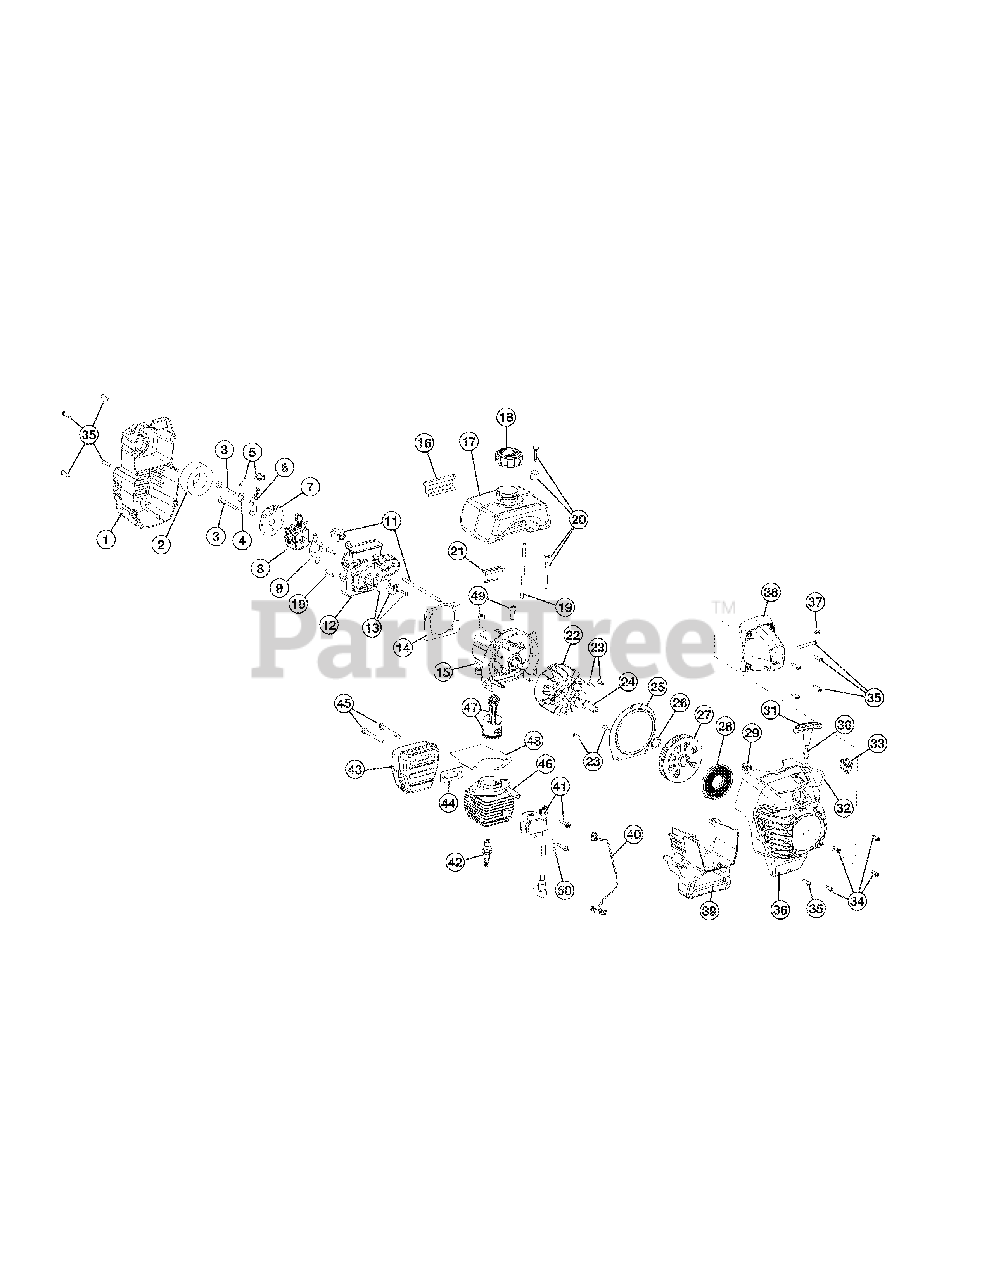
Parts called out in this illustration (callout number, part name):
1	Air Cleaner Cover Assembly (includes 2 & 35)
2	Air Cleaner Filter
3	Carburetor Mounting Screws
4	Wavey Washer
5	Choke Knob & Screw
6	Choke Lever Assembly (includes 5)
7	Choke Lever & Plate (includes 6)
8	Carburetor Assembly (includes 9 & 20)
9	Carburetor Gasket
10	Carb Mount Screw
11	Primer and Hose Assembly
12	Carburetor Mount Assembly (includes 10, 13 & 14)
13	Reed Assembly
14	Carburetor Mount Gasket
15	Crankcase Service Assembly (includes 10 & 23)
16	Rear Mounting Pad
17	Fuel Tank Assembly (includes 18 & 20)
18	Fuel Cap Assembly
19	Fuel Return Line
20	Fuel Line Assembly
21	Front Mounting Pad
22	Flywheel Assembly
23	Screw
24	Square Nut Drive
25	Pulley Retainer Assembly (includes 23 & 29)
26	Palnut
27	Recoil Pulley Assembly (includes 26 & 32)
28	Recoil Spring
29	Rope Guide Retainer
30	Pull Handle
31	Rope Guide
33	Switch Assembly (includes 40)
34	Housing Screw
35	Cover Screw
36	Starter Housing Assembly (includes 23, 25-32, 34 &35)
37	Anti-Rotation Screw
38	Clutch Cover Assembly (includes 35 & 37)
39	Shroud Extension and Stand (includes 35)
40	Wire Lead
41	Module Assembly
42	Spark Plug
43	Muffler Assembly (includes 44 & 45)
44	Exhaust Gasket
45	Muffler Mounting Bolt Assembly
46	Cylinder Assembly (includes 48 & 49)
47	Piston & Rod Assembly
48	Cylinder Gasket
49	Cylinder Bolt
50	Ground Tab
